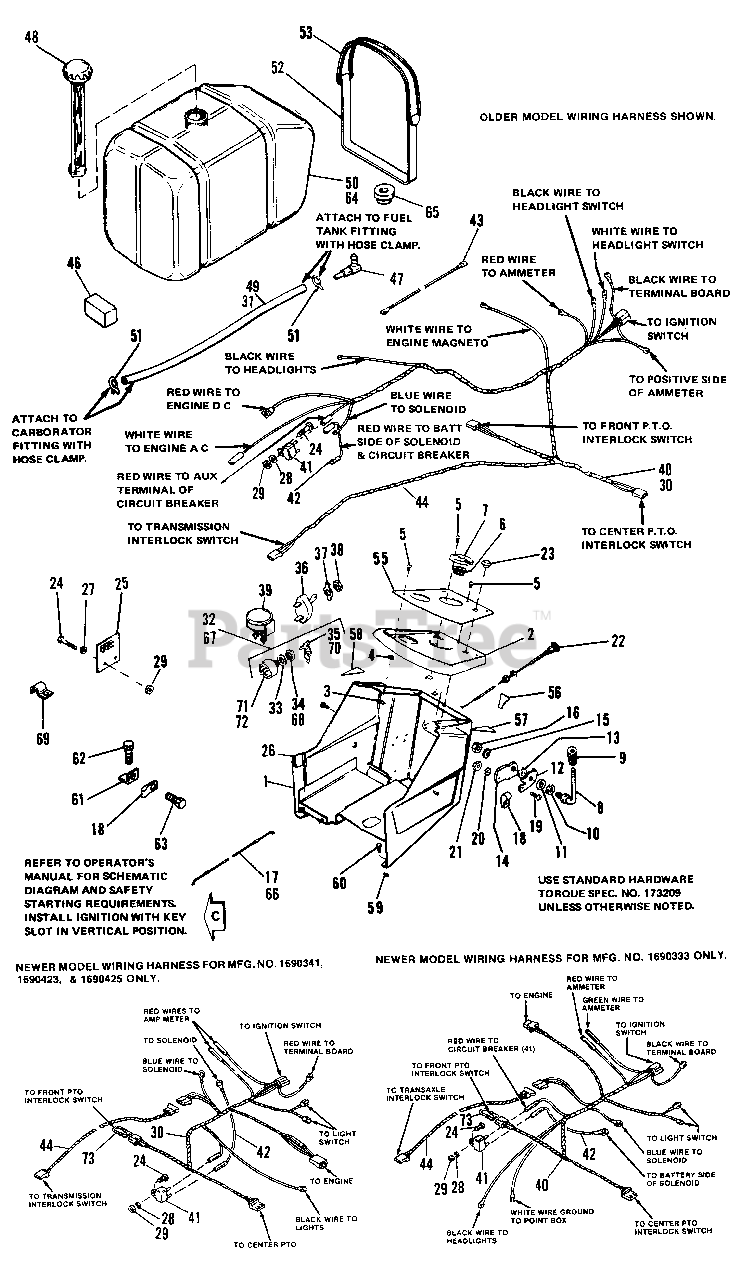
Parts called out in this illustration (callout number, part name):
1	DASH ASSEMBLY
2	PANEL, Instrument
3	NUT, Retainer, Tinn.
4	WASHER, Plain, 3/16
5	SCREW, Mach. Rd. Hd., 1/4-20 x 1/2
7	PLATE STEERING, Adj.
8	HANDLE, Clutch Control
9	KNOB, Tapered
12	STOP, Throttle Kit
14	ARM, Throttle
15	LOCKWASHER, Dished Shakeproof, 3/8
16	LOCKNUT, Hex, 3/8-16
17	CONTROL, Throttle (7016 0nly)
18	CLIP, Bowden Wire (7010 Quantity 1 Only)
19	SCREW, Rd. Hd., No. 10-32 x 1/2
20	LOCKWASHER, External, No. 10
21	NUT, Mach. Hex, No. 10-32
22	CONTROL, Choke
23	PLUG, Button
24	CAPSCREW, Hex Hd., 1/4-20 x 5/8
25	BOARD, Terminal
26	CLIP, Wire
27	NUT, Lock, Hex, 1/4-20 UNC 2B
28	LOCKWASHER, Shakerproof, 1/4
29	NUT, Hex, 1/4-20
30	HARNESS ASSY. (1690333 Only)
30	HARNESS ASSY. (1690341 Only)
31	HOSE, Fuel (7010 0nly)
32	SWITCH KEY ASSY. (7016 Only)
33	LOCKWASHER, internal, 5/8
34	NUT, Hex Special (7016 Only)
35	KEY, Set (7016)
36	SWITCH, Toggle
37	PLATE
38	NUT
40	HARNESS ASSEMBLY (1690423 Only)
40	HARNESS ASSEMBLY (1690425 Only)
41	CIRCUIT BREAKER
42	WIRE ASSEMBLY
43	WIRE ASSEMBLY (7010 0nly)
44	WIRE ASSY.
46	PAD, Fuel Tank (7016 Only)
48	CAP, Fuel Tank
49	HOSE, Fuel (7016 Only)
50	TANK ASSY, Fuel, (7016 Only) Inc. Ref. No's 47, 49, 65 & 51
51	CLAMP, Hose
52	STRAP, Tank
53	STRAP, Fuel Tank
55	DECAL, Instrument Panel
56	DECAL, Ignition
57	DECAL, Throttle Control
58	DECAL, 6-Speed Control
59	NUT, Speed, Tinn.
60	SCREW, Hex Hd. Thd. Forming, No. 14 x 3/4
61	BRACKET, Cable (7016 Only)
62	SCREW, Hex Hd., 1/4-20 x 5/8 (7016 Only)
63	SCREW, Taptite, No. 10-24 x 1/2 (7016 Only)
64	TANK ASSY, Fuel (7010 Only) Incl. Ref. Nos. 31, 47, 65, 51)
66	CONTROL, Throttle (7010 Only)
67	SWITCH KEY ASSY. (7010 Only)
68	NUT, Hex, Special (7010 Only)
69	CLIP, Cable
70	KEY, Set (7010 Only)
71	SWITCH, Ignition (7016 Only)
72	SWITCH, Ignition (7010 Only)
73	WIRING ASSEMBLY
